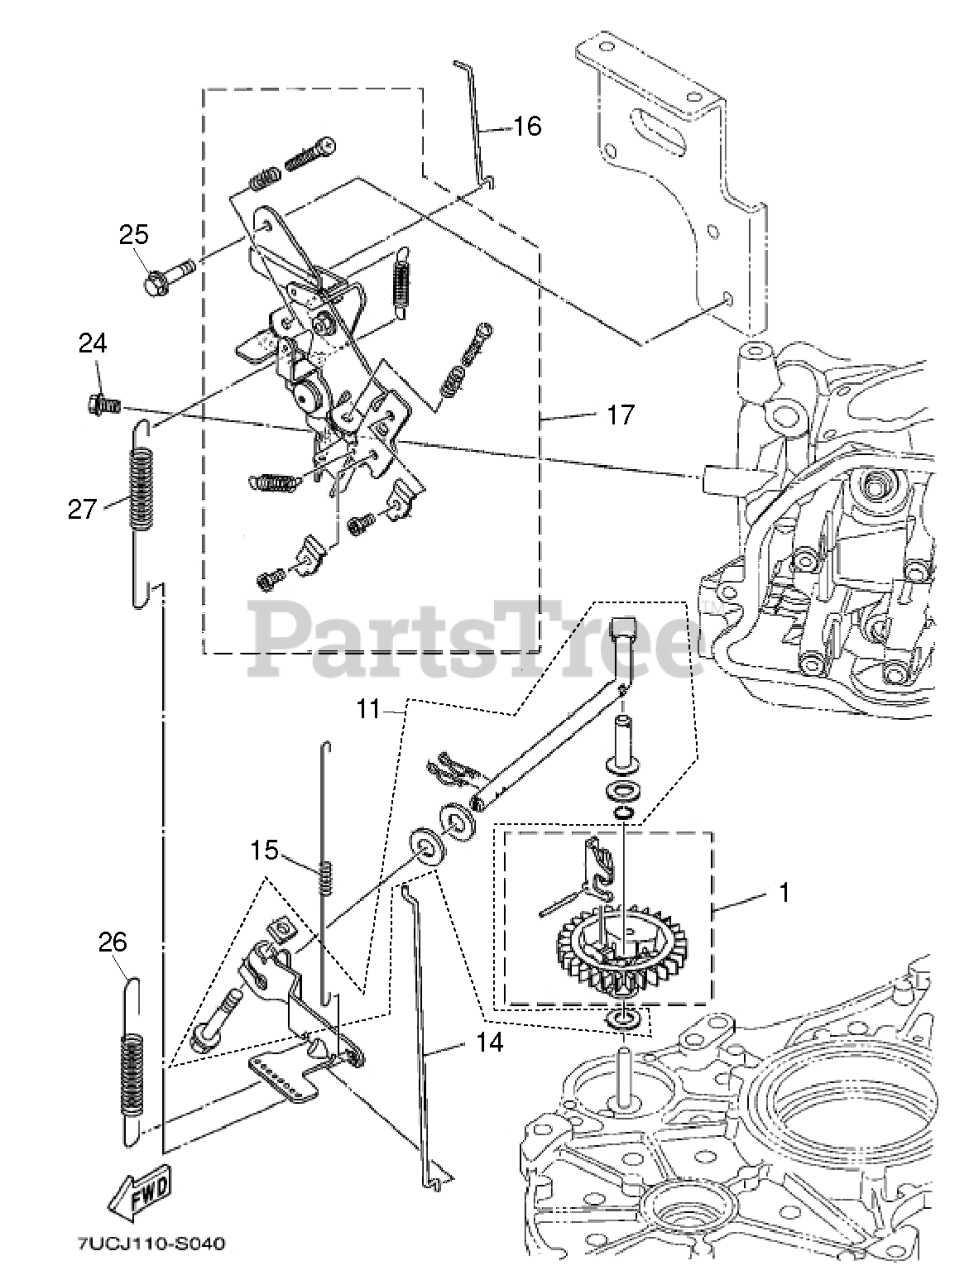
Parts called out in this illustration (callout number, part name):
1	GOVERNOR KIT
11	SHAFT ASSY FLYWEIGHT YAMAHA PN
14	ROD LINK YAMAHA PN: 7UC-E1928-
15	SPRING TENSION YAMAHA PN: 9050
16	ROD CHOKE 1 YAMAHA PN: 7UC-G 1
17	THROTTLE LEVER COMP YAMAHA PN:
24	BOLT YAMAHA PN: 95802-06012
25	BOLT YAMAHA PN: 95802-06020
26	SPRING GOVERNOR YAMAHA PN: 7UD
27	SPRING TENSION YAMAHA PN: 9050
